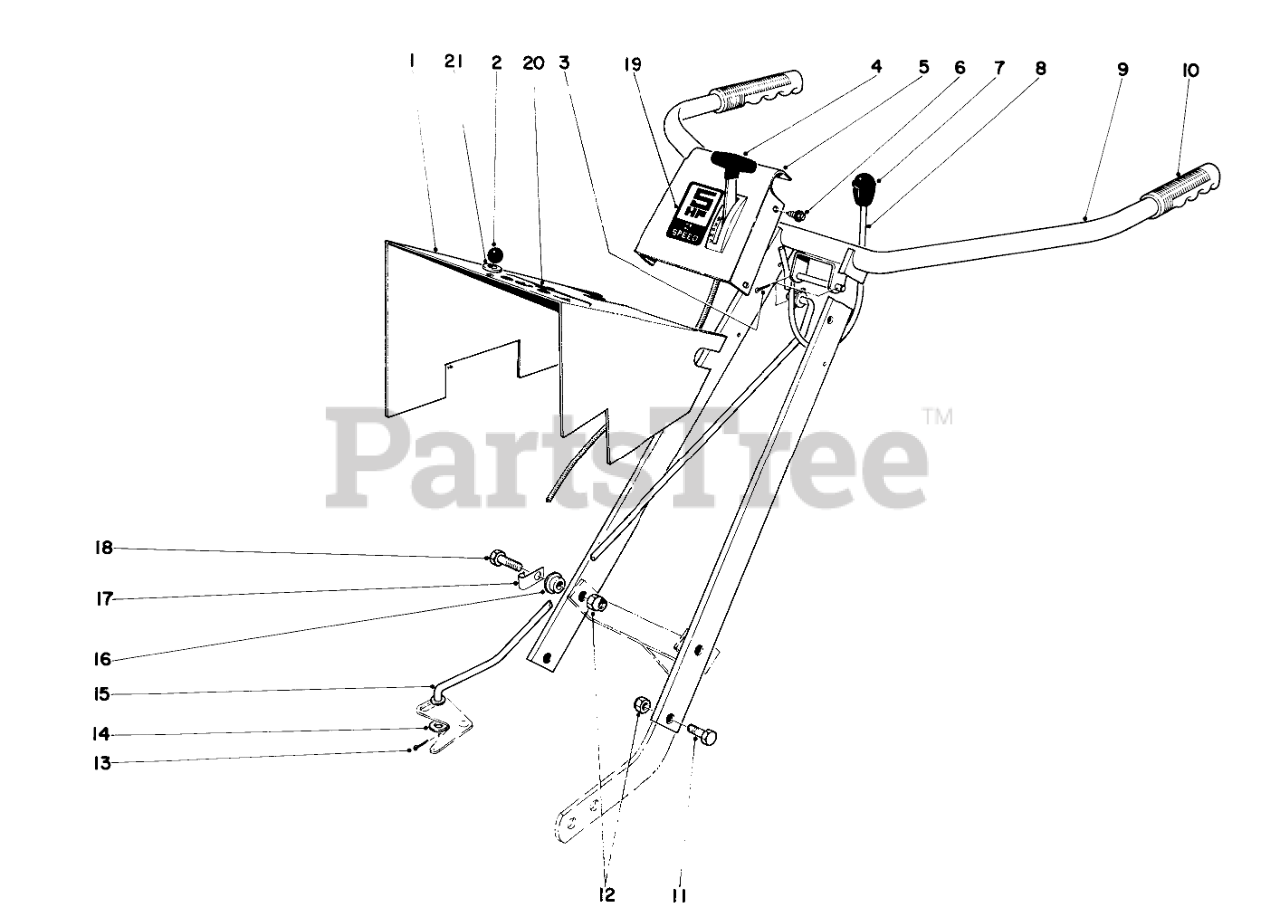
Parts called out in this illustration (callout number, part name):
1	Pulley Cover
3	PIN-COTTER
4	Throttle
5	Cover Handle
6	10-16 X 3/8 THDG SCREW
7	Knob
8	Shift Lever
9	Handle Bar
10	Handle Grip
11	SCREW-HH
12	NUT-LOCK, CONE
13	PIN-COTTER
14	Washer
15	Clutch Rod
16	Spacer
18	SCREW-HH
19	Decal
20	Decal
21	WASHER-FLAT
